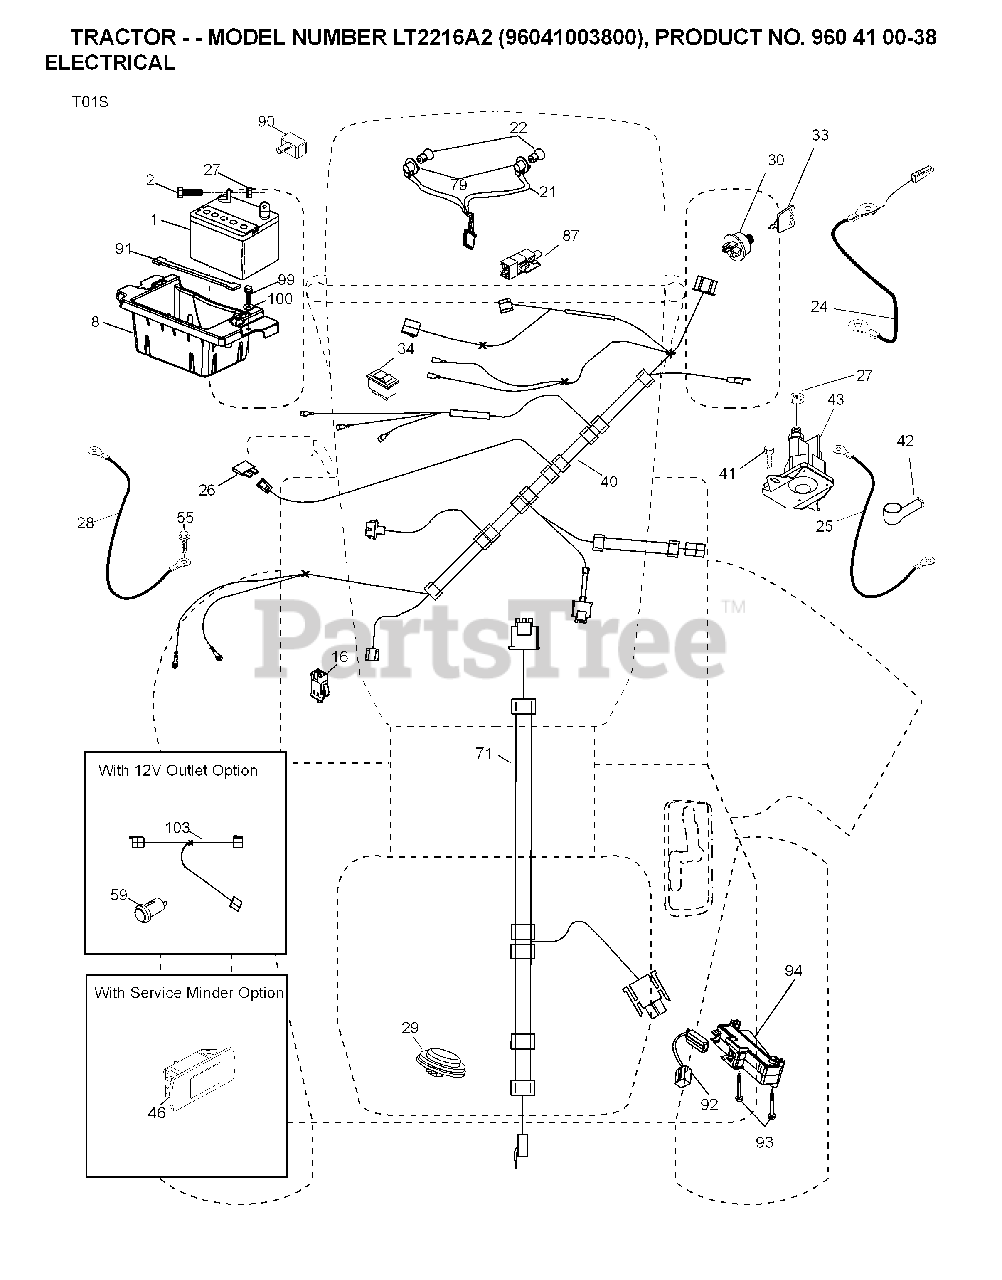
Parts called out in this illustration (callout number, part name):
1	BATTERY 12V .35 AMP
8	BOX.BATTERY.MOUNT.FRONT.LT
16	SWITCH INTERLOOK PUSH-IN
21	HARNESS ASSY LIGHT
22	LIGHTBULB
24	CABLE.BATT.POS.WIRE.TG.DA SOL
25	CABLE.STARTER.6GA.RED.
26	FUSE 20AMP
27	NUT
28	CABLE GROUND 6 GA 21" 90T BLK
29	SWITCH.SEAT.DELTA.OPC.
30	SWITCH.IGN.DELTA.W.LGH.ROS
33	KEY MLD GEN DELTA
34	SWITCH LT
40	HARNESS IGN. DASH
41	SCREW
42	TERMINAL COVER
43	SOLENOID.W/BRASS.PLUNG
46	GUAGE.SRVCMNDR.HRMTR.
55	SCREW 5/16"
71	HARNESS-CHASSIS SUB
79	BULB HOLDER ASM.
87	SWITCH.INTRLCK.CLUTCH.
90	COVER.TERMINAL.BATTERY
91	STRAP, BATTERY MOUNT
92	HARNESS.PIGTAIL.CONSLE
93	SCREW.PLASTITE
94	MODULE.REVERSE.ROS
99	SCREW HEXWSHR 1/4-20X3/4
